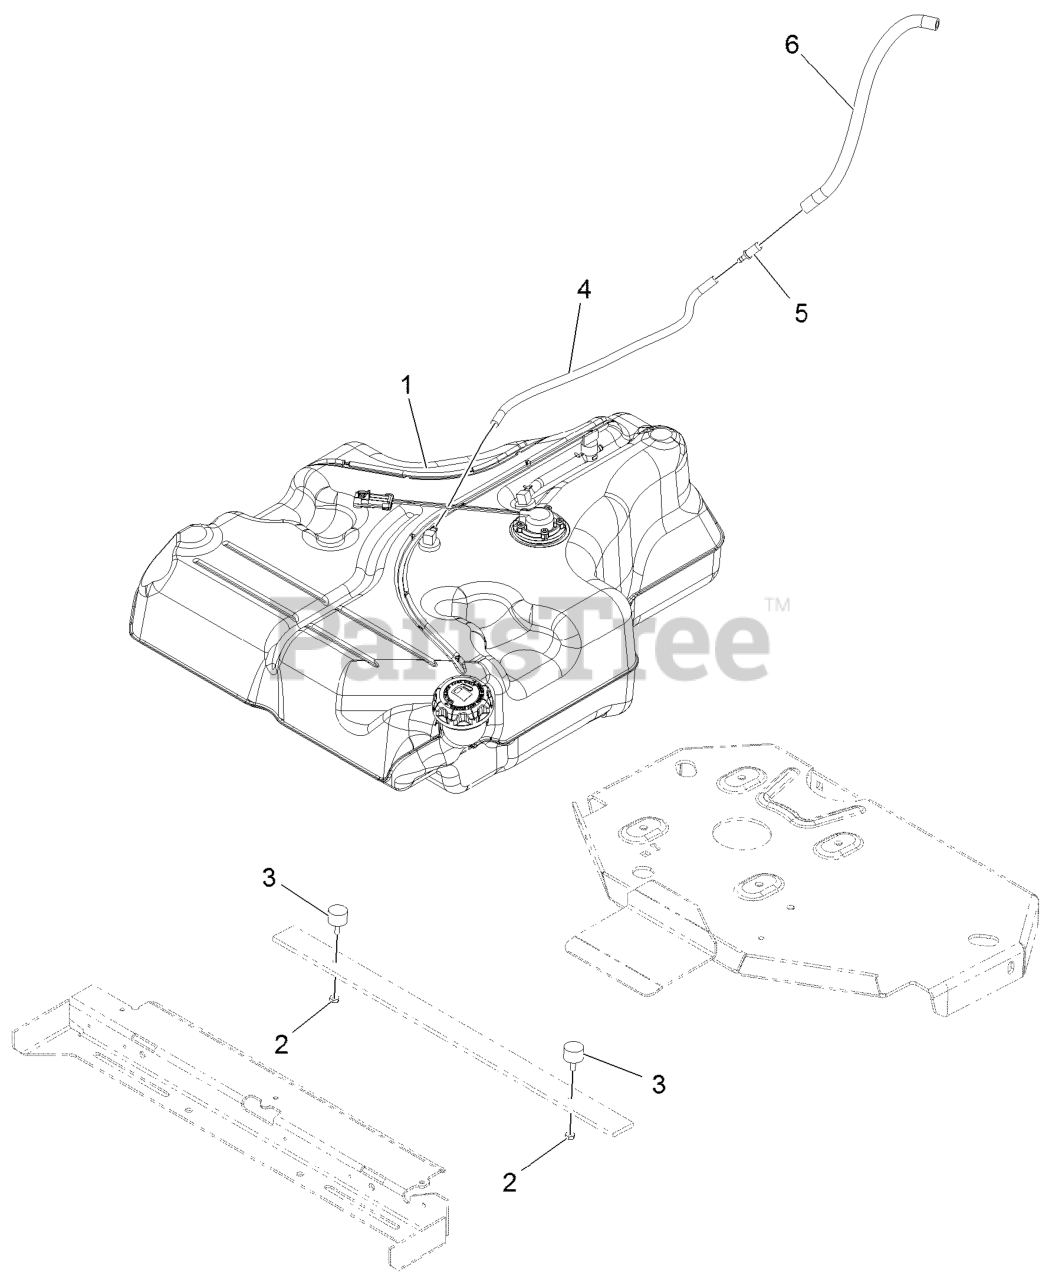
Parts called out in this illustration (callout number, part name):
2	NUT-JAM
4	HOSE-FUEL
5	FITTING-STRAIGHT
6	HOSE-FUEL
